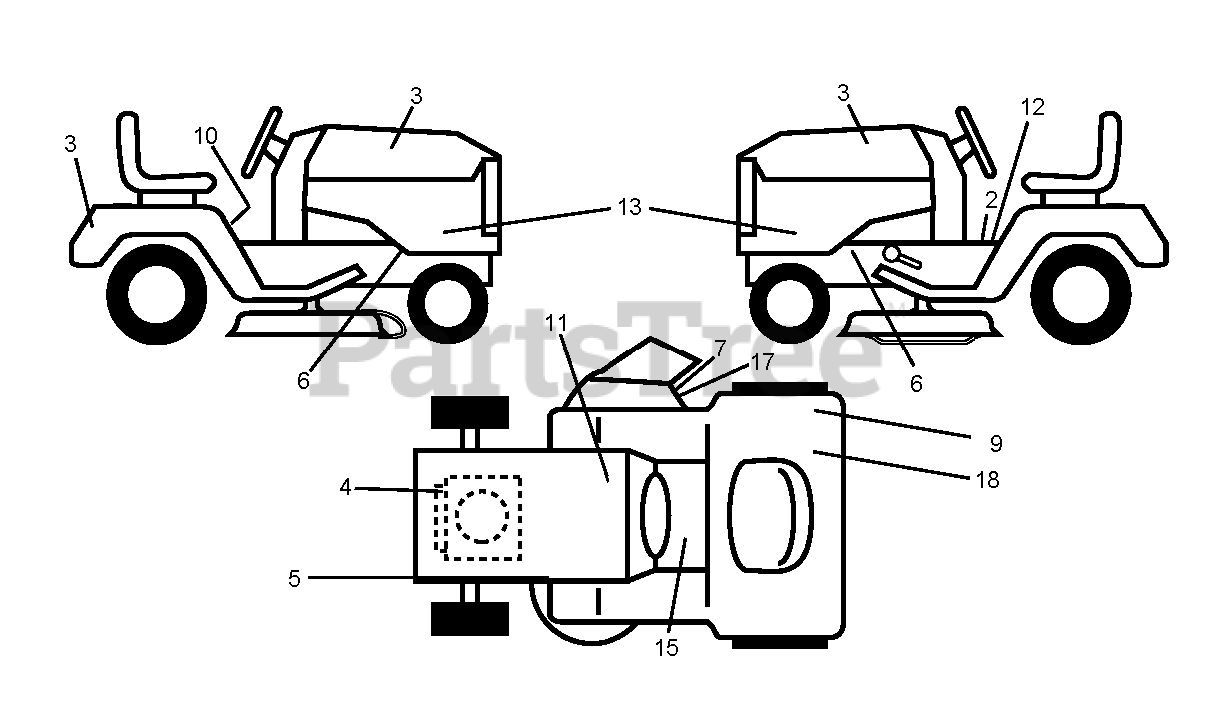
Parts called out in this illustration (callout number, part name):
2	DECAL PARK BRAKE
3	DECAL.HOOD.LOGO.ORANGE.HUSQVAR
4	DECAL
5	DECAL V BELT SCHEMATIC
7	DECAL.INTERNATIONL.CUTFINGER
9	DECAL
10	LABEL
11	DECAL BTRY SYMBOLS
12	DECAL
15	DECAL
17	DECAL, DEFLECT WARNING
18	DECAL 80 DBA
